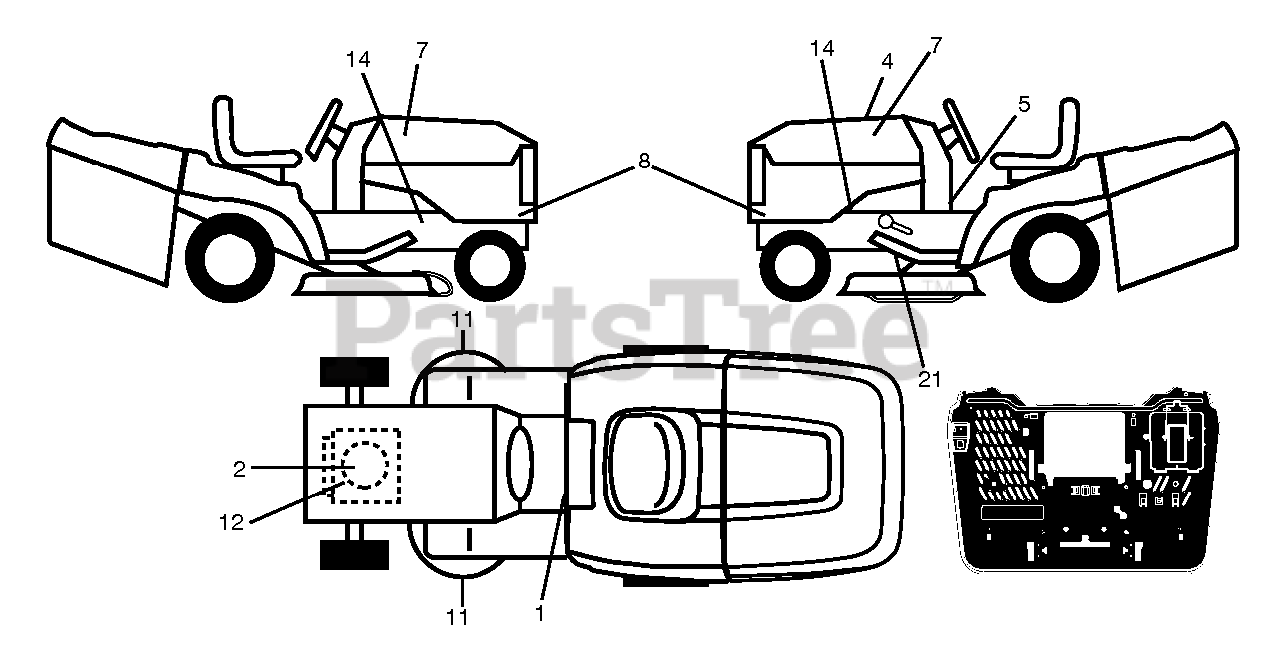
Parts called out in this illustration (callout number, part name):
1	DECAL.TRAC.FNDR.GLBLWRNG.RDYST
2	DECAL.ENGINE.WARNING
4	DECAL.RPL.BSM40.END.TCRD.97R.
5	Decal, Instruction MLCH/BG VERT
7	DECAL.BADGE.170MM.TEXTLOGO.
8	DECAL.SDPNL.HUSQGT.TC238.RH/LH
11	DECAL.CUTFINGER.CE.02
12	DECAL DECAL.ENG.BS.ENDUR.20HP.
14	DECAL.CHASSIS.HOT.MUFFLER
21	DECAL DECAL V-BELT 97 CM CRD
